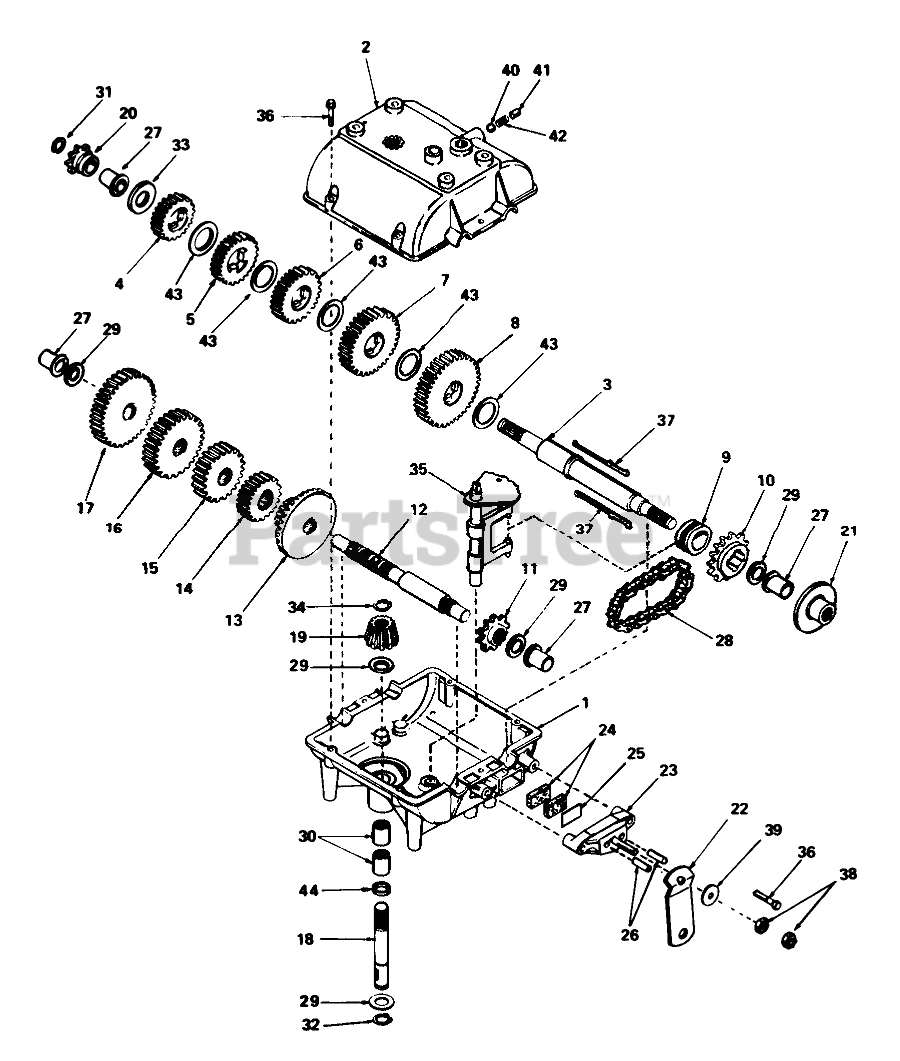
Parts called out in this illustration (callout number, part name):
1	Case-Transmission
2	Cover-Transmission
3	Shaft-Output & Brake
4	Gear-Spur 20 teeth
5	Gear-Spur (22 teeth)
6	Gear-Spur, 25 Teeth
7	Gear-Spur, 30 Teeth
8	Gear-Spur, 35 Teeth
9	Collar-Shift
10	Sprocket-18 Teeth
11	Sprocket-9 Teeth
12	Countershaft
13	Gear-Bevel (42 tooth & 15 tooth spur gear)
14	Gear-Spur, 20 Teeth
15	Gear-Spur, 25 Teeth
16	Gear-Spur (28 teeth)
17	Gear-Spur (30 teeth)
18	Shaft-Input
19	Bevel Pinion-Input
20	Sprocket (8Teeth)
21	Disk
22	Lever Brake
23	Holder-Brake Pad
24	Brake Pad
25	Brake Pad Plate
26	Dowel Pin
27	Bushing, Flanged
28	Chain-Roller #41
29	Washer
30	Bearing-Needle
31	Piston Asm (.020 O S)
32	Ring-Snap
33	Washer
34	Ring-Retainer
35	Rod and Fork ASM
36	Ring Set (.020 O S)
37	Key
38	Locknut
39	Washer
40	Ball-Steel
41	Screw-Set
42	Spring
43	Washer
44	O Ring
